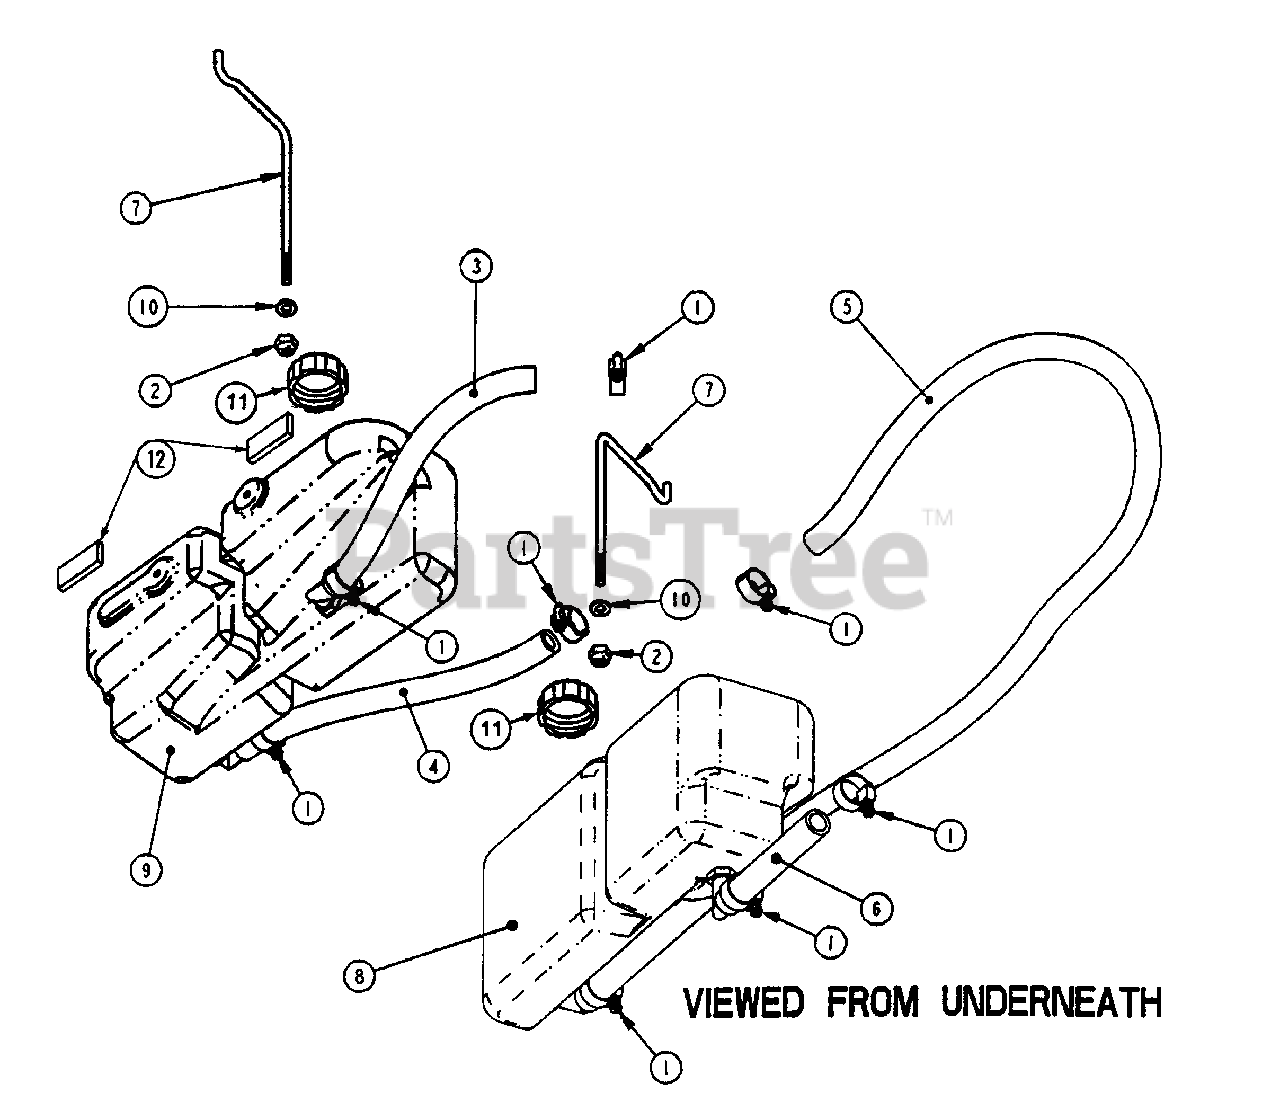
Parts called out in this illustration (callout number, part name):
1	CLAMP, Hose 13/16"
2	NUT, 5/16-18 HEX NYLON LOCK
3	HOSE, Rubber R.H. Front (13-1/2")
4	HOSE, Rubber R.H. Back (16")
5	HOSE, Rubber L.H. Front (34")
6	HOSE, Rubber L.H. Back (6")
7	BRACKET, Reservoir
8	RESERVOIR, L.H. Hydro
9	RESERVOIR, R.H. Hydro
10	WASHER, 11/32" I.D. x 11/16" O.D.
11	CAP, Reservoir
12	PAD, Tank
